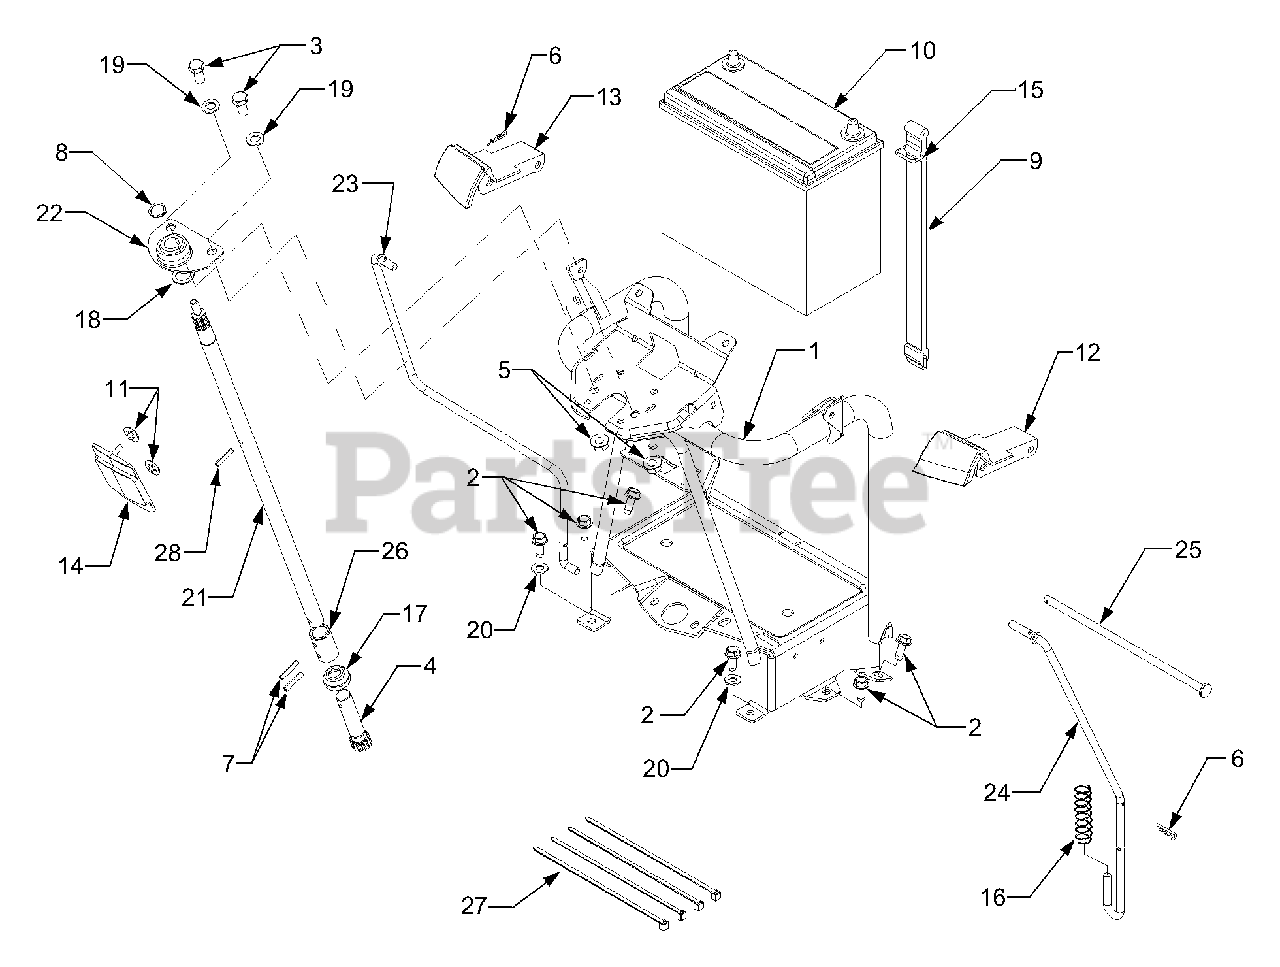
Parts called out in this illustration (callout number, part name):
1	Pedestal Assembly
2	Screw, Hex Wash. Hd. Tapp 5/16-18 x .75
3	Screw, Hex Cap 3/8-16 x .75 GR5
4	Shaft, Lower Steering
5	Nut, Hex Flange Lock, 3/8-16
6	Pin, Internal Cotter
7	Pin, Spirol, 3/16 x 1.0
8	Ring, Retaining, .56 Dia Shaft
9	Strap, Battery
10	Battery
11	Push Nut, .188 Dia.
12	Lever, Park Brake
13	Lever, Cruise
14	Cover, Fixed Steering
15	Hook, Wire Rectangular
16	Spring, Compression, .676 x 2.57
17	Boot, Shaft Cover
18	Washer, Flat, .635 x .93 x .06
19	Washer, Flat, .375 x .738 x .063
20	Washer, Flat, .344 x .688 x .065
21	Shaft, Upper Steering
22	Bearing, Steering Support
23	Rod, Cruise Control
24	Rod, Parking Brake
25	Rod, Cruise/Brake Pivot
26	Sleeve, Fixed Steering
27	Cable Tie, Harness
28	Pin, Spirol, 1/8 x .812
